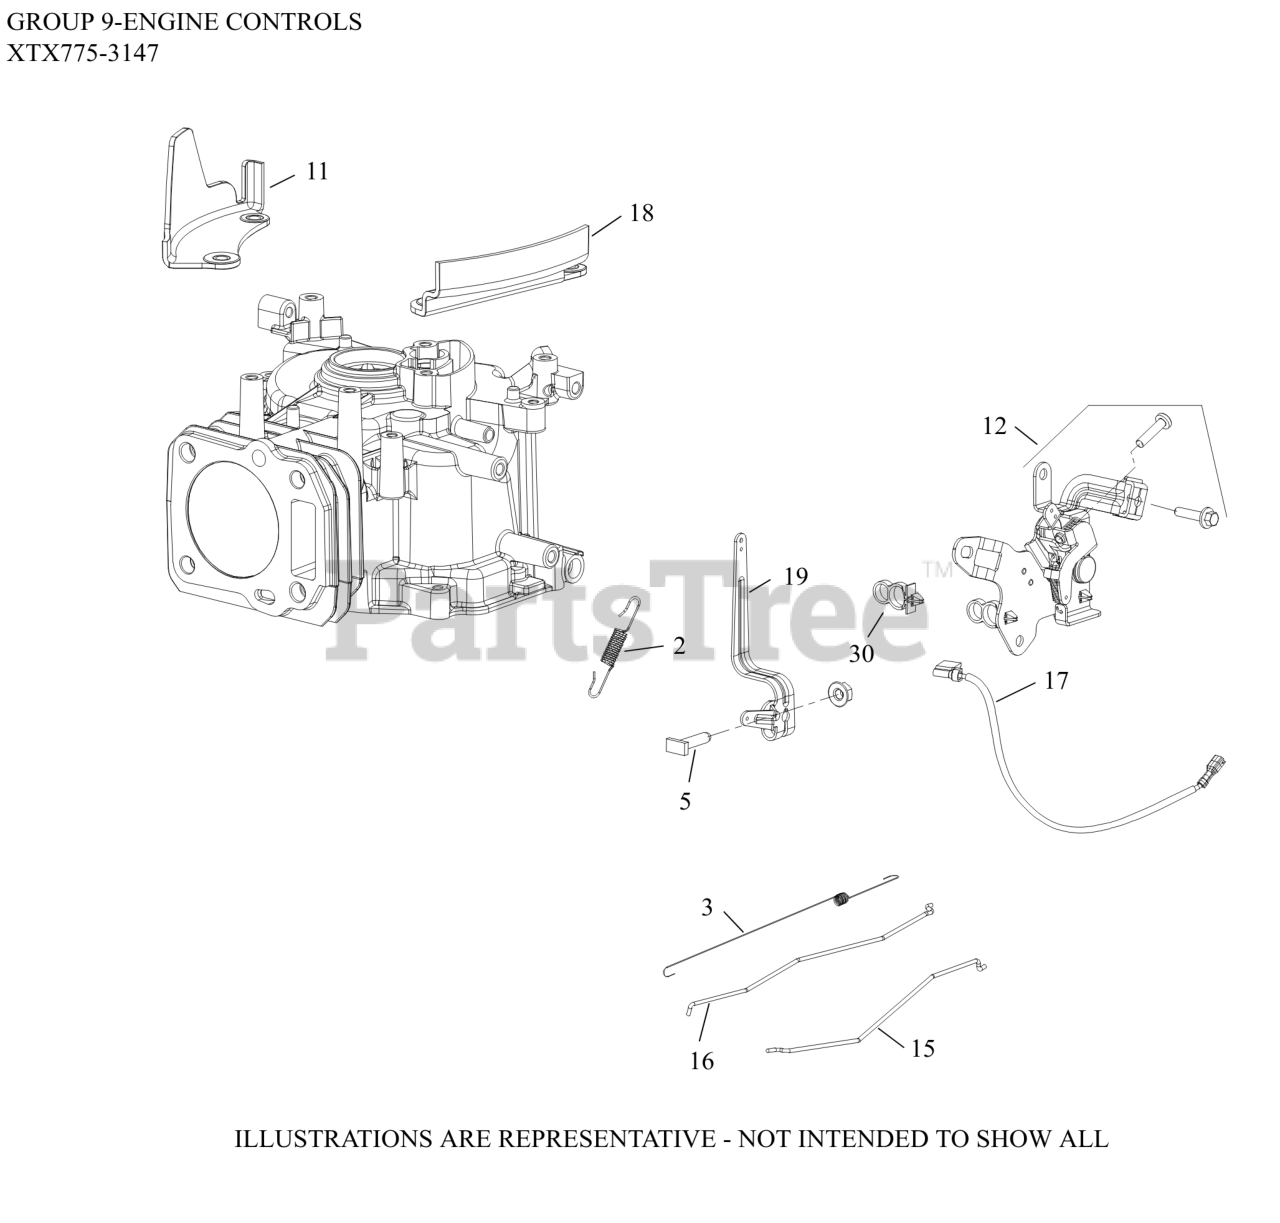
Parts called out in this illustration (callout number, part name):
2	SPRING, GOV (2800-3300 RPM)
3	SPRING, LINKAGE
5	SCREW, RECTANGLE HEAD (M6)
11	GUARD, FINGER
12	CONTROL ASSY, REMOTE VARIABLE SPEED
15	LINKAGE, CHOKE
16	LINKAGE, GOVERNOR
18	GUARD, FINGER
19	LEVER, GOVERNOR
30	CLIP, FUEL LINE
